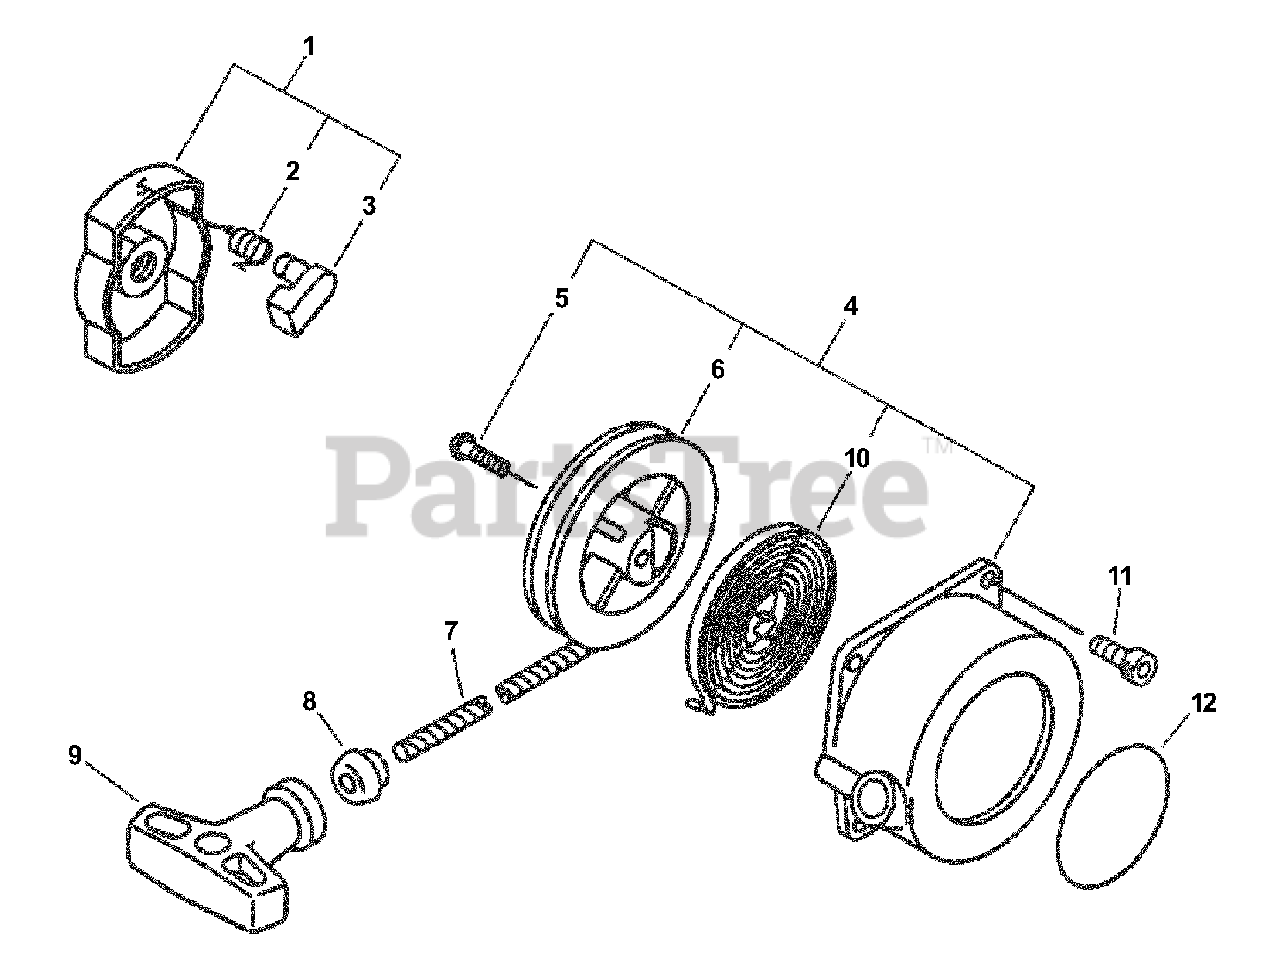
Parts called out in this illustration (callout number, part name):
1	PAWL ASSY, STARTER
2	SPRING, RETURN
3	PAWL, STARTER - BLACK
4	STARTER ASSY
5	SCREW
6	REEL, ROPE
7	ROPE, STARTER
8	GUIDE, ROPE
9	GRIP, STARTER
10	SPRING, RECOIL
11	BOLT 4×16
12	LABEL, ECHO
